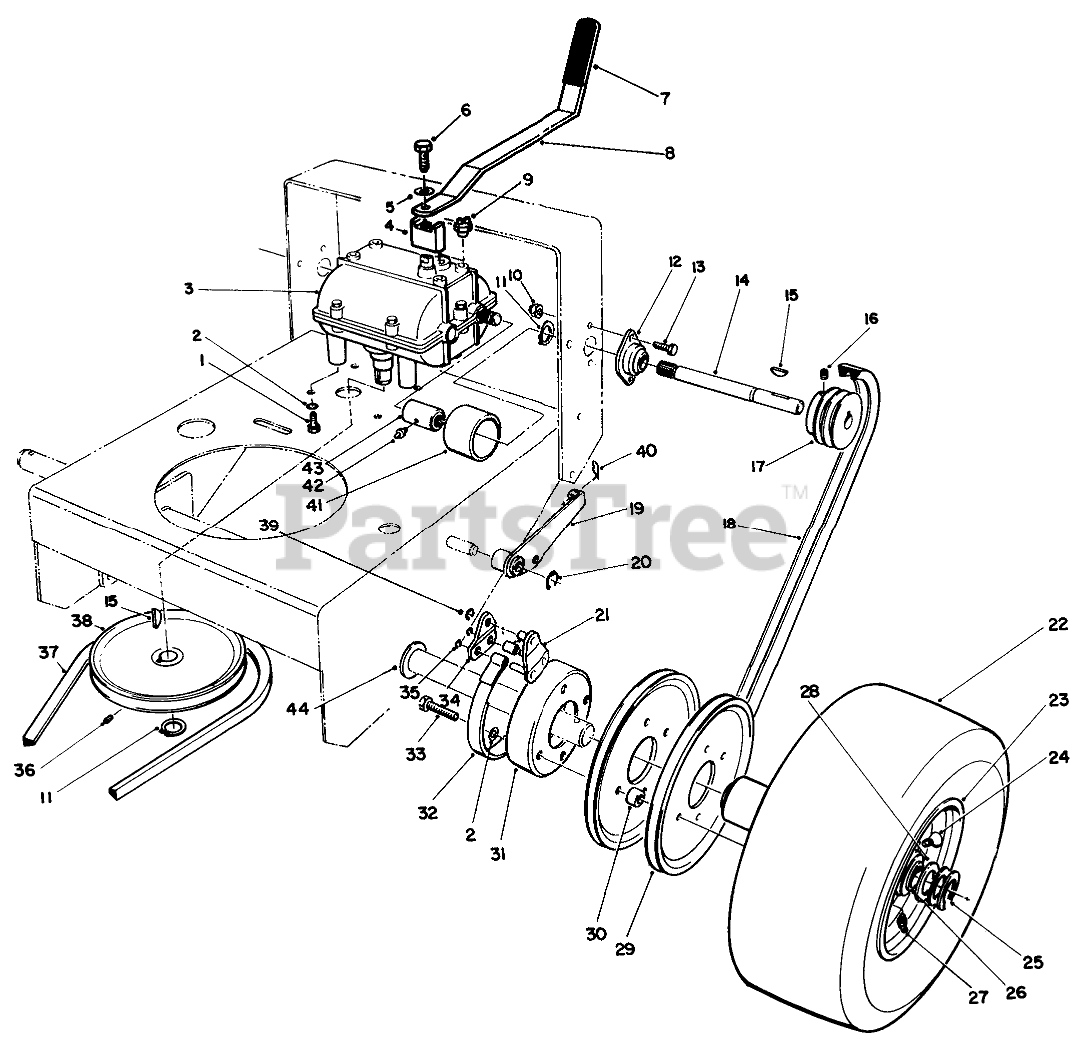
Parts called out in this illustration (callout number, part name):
1	SCREW-HH
2	WASHER-LOCK
3	TRANSMISSION
4	MOUNT-LEVER, SHIFT
5	SPACER
6	SCREW-HH
8	SHIFT LEVER R
9	NEUTRAL SWITCH
10	NUT-LOCK, NI
11	RING-SNAP, EXTERNAL
12	BEARING-EXTERNAL SHAFT
13	SCREW-HH
14	SHAFT-EXTENSION, LH
15	KEY-WOODRUFF
16	SCREW-SET, HS
17	Pulley-Drive
18	V-BELT
19	Brake Arm-LH
20	RING-RETAINING
21	LINK-BRAKE
23	WHEEL AND HUB ASM
24	STEM-VALVE
25	RING-RETAINING
26	BEARING-BALL, FLANGED
27	FITTING-LUBE, 45 DEG
28	WASHER-THRUST
29	Pulley-Wheel
30	SPACER-PULLEY
31	Drum-Brake
32	BAND-BRAKE
33	SCREW-HH
34	Plate-Link
35	RING-RETAINING
36	SCREW-SET
37	V-BELT
38	PULLEY-DRIVEN
39	RING-RETAINING, EXTERNAL
40	PIN-COTTER
41	GUARD-COUPLER
42	FITTING-GREASE
43	COUPLER
44	WASHER-WHEEL
